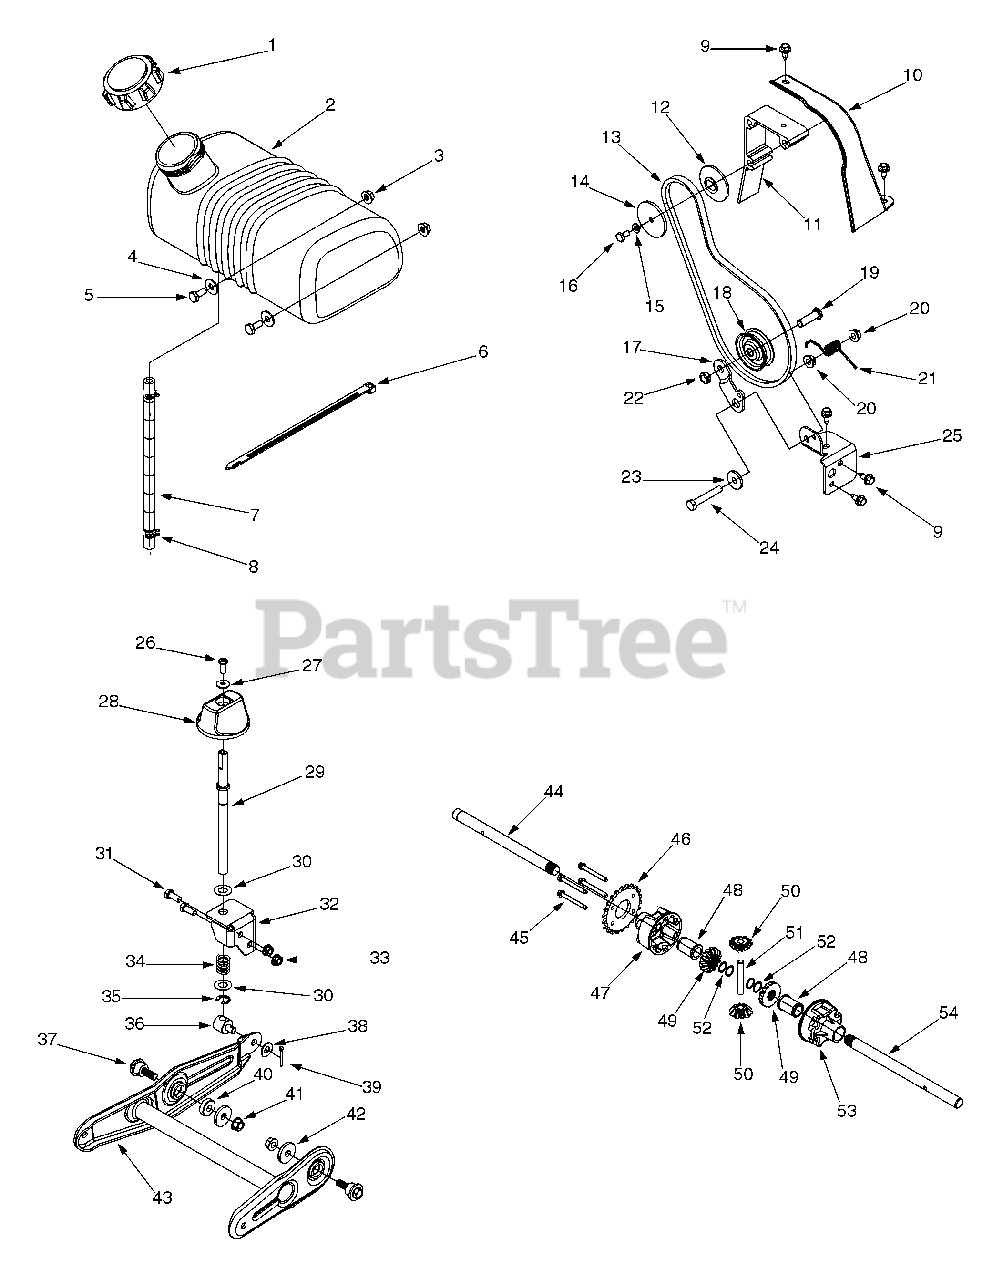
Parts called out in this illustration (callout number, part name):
1	Fuel Cap
2	Gas Tank - 1 Gallon
3	Hex Lock Nut 1/4-20
4	Flat Washer .28 ID x .74 OD
5	Hex Cap Screw 1/4-20 x .620
6	Cable Tie
7	Fuel Line
8	Hose Clamp
9	Hex Washer Screw 1/4-14 x .625
12	Pulley Half
13	V-Belt
14	Pulley Half
15	Lock Washer 1/4
16	Hex Cap Screw 1/4-28 x .50
17	Idler Bracket
18	Flat Idler
19	Hex Cap Screw 3/8-16 x 1.25
20	Hex Lock Nut 5/16-18
21	Torsion Spring
22	Lock Nut 3/8-16
23	Shoulder Spacer
24	Hex Cap Screw 5/16-18 x 2.0
27	Bell Washer .265 ID x .75 OD
28	Knob
29	Height Adjustment Rod
30	Flat Washer .508 ID x 1.0 OD
31	Hex Cap Screw 5/16-18 x .75
34	Compression Spring
35	E Ring
36	Adjustment Ferrule
37	Shoulder Screw 3/8-16
38	Flat Washer .406 ID x .875 OD
39	Cotter Pin
41	Flange Lock Nut 3/8-16
42	Flat Washer .375 ID x 1.25 OD
45	Hex Washer Screw 1/4-20 x 2.375
46	Sprocket 22T
47	Differential Housing LH
48	Flange Bearing .75 ID x 1.0 OD x 1.5
49	Differential Gear 14T
50	Differential Gear 10T
51	Cross Shaft .427 x 2.7
52	Retaining Ring
53	Differential Housing RH
54	Axle Shaft .750 x 10.954
